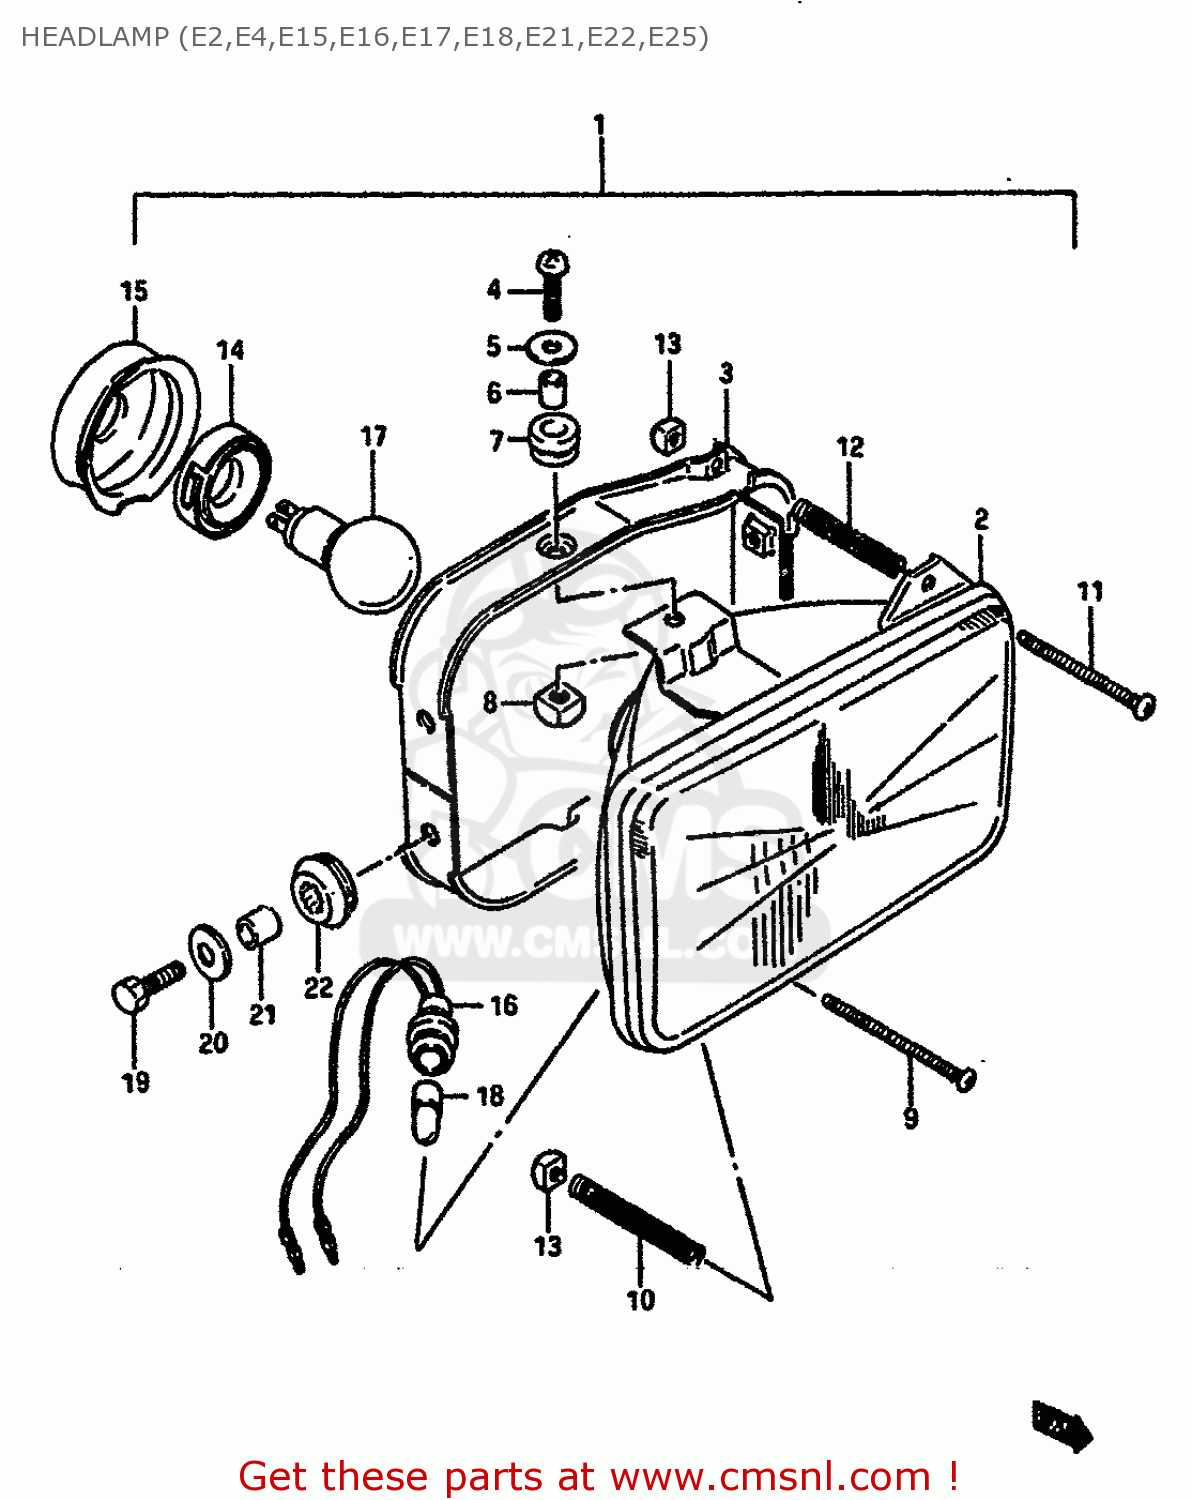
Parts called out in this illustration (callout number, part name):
1	HEADLAMP ASSY
2	LAMP UNIT
3	HOUSING
4	SCREW(5X14)
5	WASHER
6	SPACER
7	CUSHION
8	NUT
9	SCREW,HEADLAMP ADJUST
10	SPRING
11	SCREW,HEADLAMP ADJUST
12	SPRING
13	NUT
14	HOLDER,BULB
15	COVER,SOCKET
16	SOCKET,PARKING
17	BULB(12V45/40W)
18	BULB(12V4W)
19	BOLT
20	WASHER (6.5X20X1.2)
21	SPACER (6.1X9X9)
22	CUSHION
